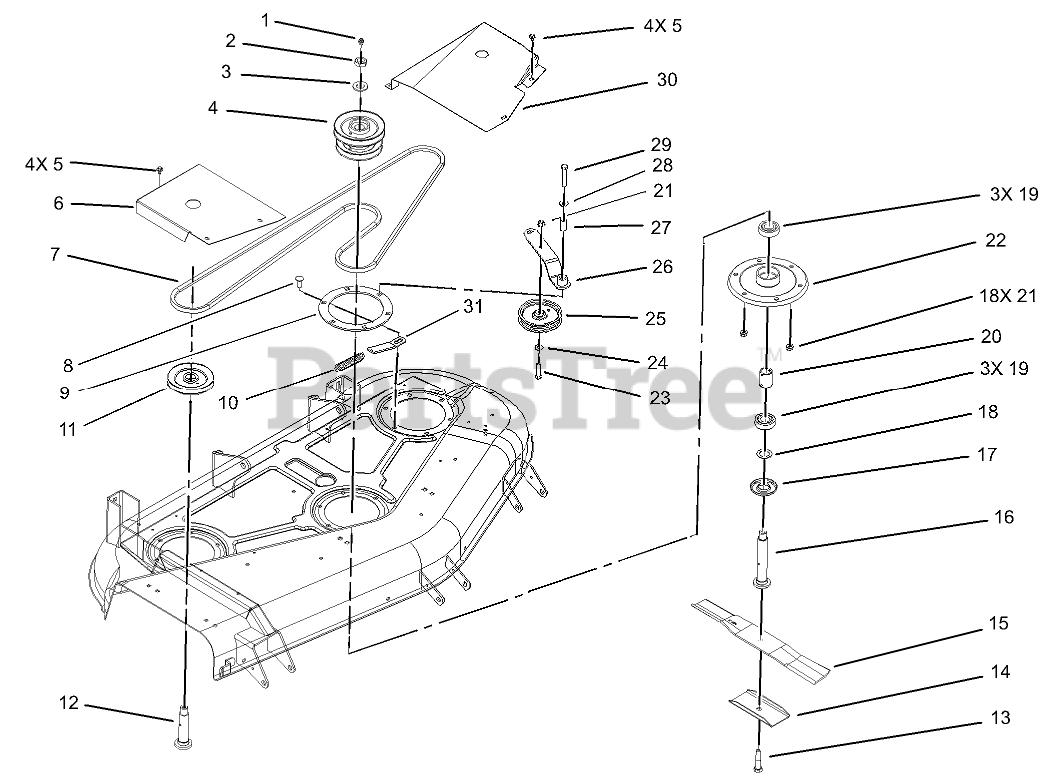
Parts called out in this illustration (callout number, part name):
1	FITTING-GREASE
2	NUT-JAM
3	WASHER-FLAT
4	PULLEY-DOUBLE
5	SCREW-HHFTF
6	COVER-BELT, RH
7	V-BELT
8	SCREW-CARR
9	RING-DECK SUPPORT
10	SPRING-EXTENSION
11	PULLEY
12	SHAFT-SPINDLE
13	SCREW-BLADE
14	STIFFENER-BLADE
15	Blade
16	SHAFT-SPINDLE
17	SHIELD-BEARING
18	WASHER-WHEEL
19	BEARING-BALL
20	SPACER-BEARING
21	NUT-HF
22	HOUSING-SPINDLE
23	SCREW-HH
24	WASHER-FLAT
25	PULLEY-IDLER
26	IDLER ARM ASM
27	SLEEVE
28	WASHER-FLAT
29	SCREW-HH
30	COVER ASM-LH
31	PLATE-SPRING
